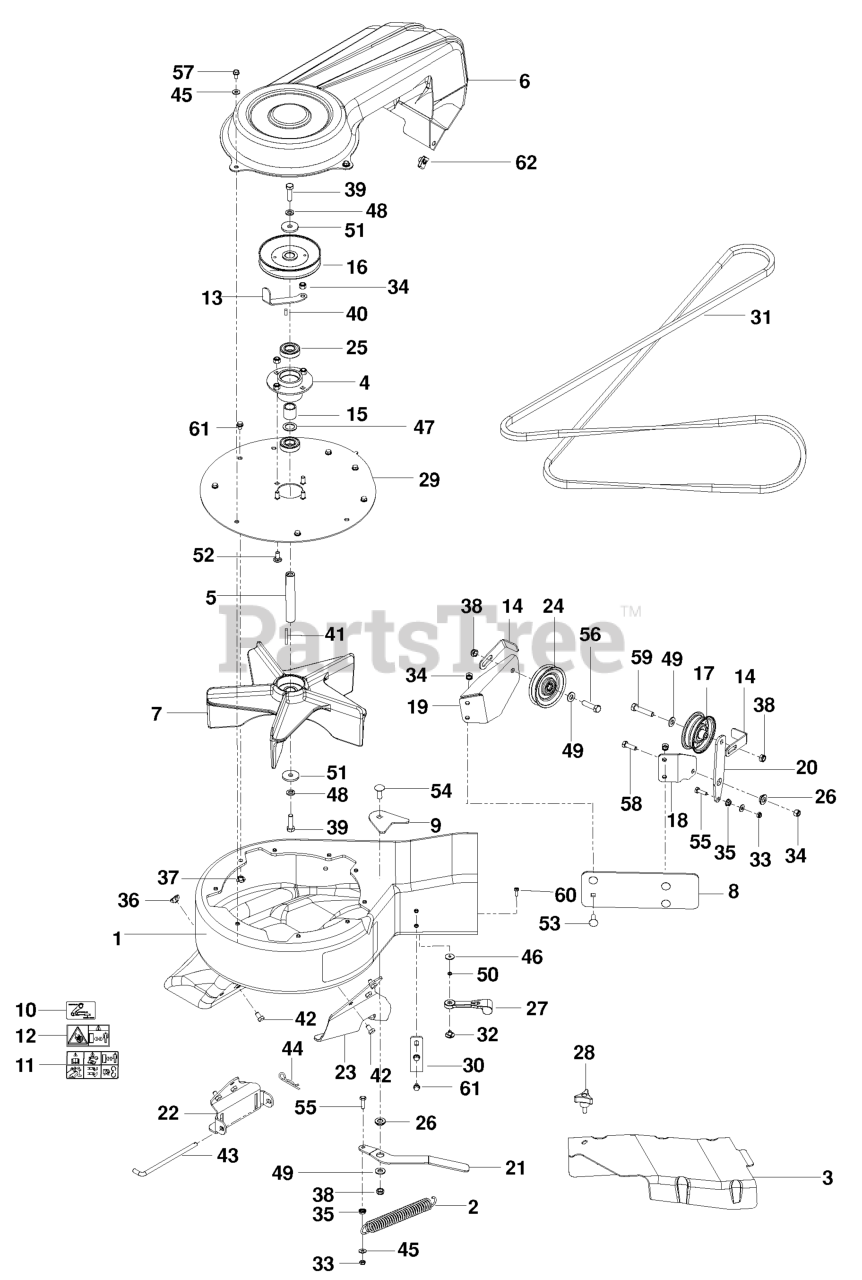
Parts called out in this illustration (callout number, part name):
2	SCREEN, COVER
3	FRAME, BAGGER
4	SEAL, COVER
5	GASKET, COVER
6	CONTAINER, SOFT BAG
7	PIN, HINGE
8	HANDLE, BAGGER COVER
9	SUPPORT, HOSE
10	FLEX TRIM, BLACK
11	PLUG, TUBING END
12	PLUG SPACER
13	WASHER 5/16 SAE FLAT
14	HCS 5/16-18 x 1 1/4
15	SCREW #10-24 x 5/8
17	NUT #10-24 CROWNLOCK
18	NUT 5/16-18 HEX NYLOC
